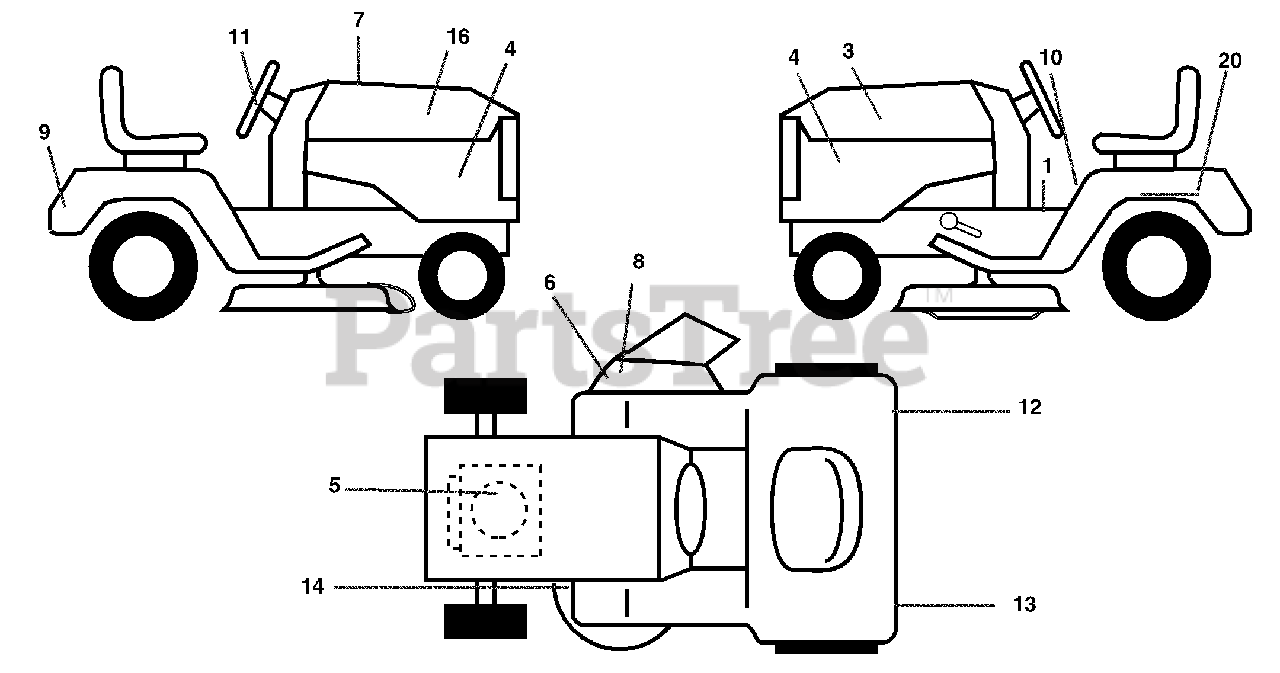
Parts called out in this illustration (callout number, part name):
3	Decal Hood LH
4	Decal Side Panel Logo
5	Decal HP Engine
6	Decal Warning, Keep Hand Away
7	Decal Replacement Parts
8	Decal Deck "B" 42"
9	Decal Fender Logo
10	Decal Fender Danger E/F
11	Decal Ins Strg Whl
12	Decal Fend Reflector Rh
13	Decal Fend Reflector Lh
14	Decal V-Belt Schematic
16	Decal Hood Rh
20	Decal Bat Dan/Psn
